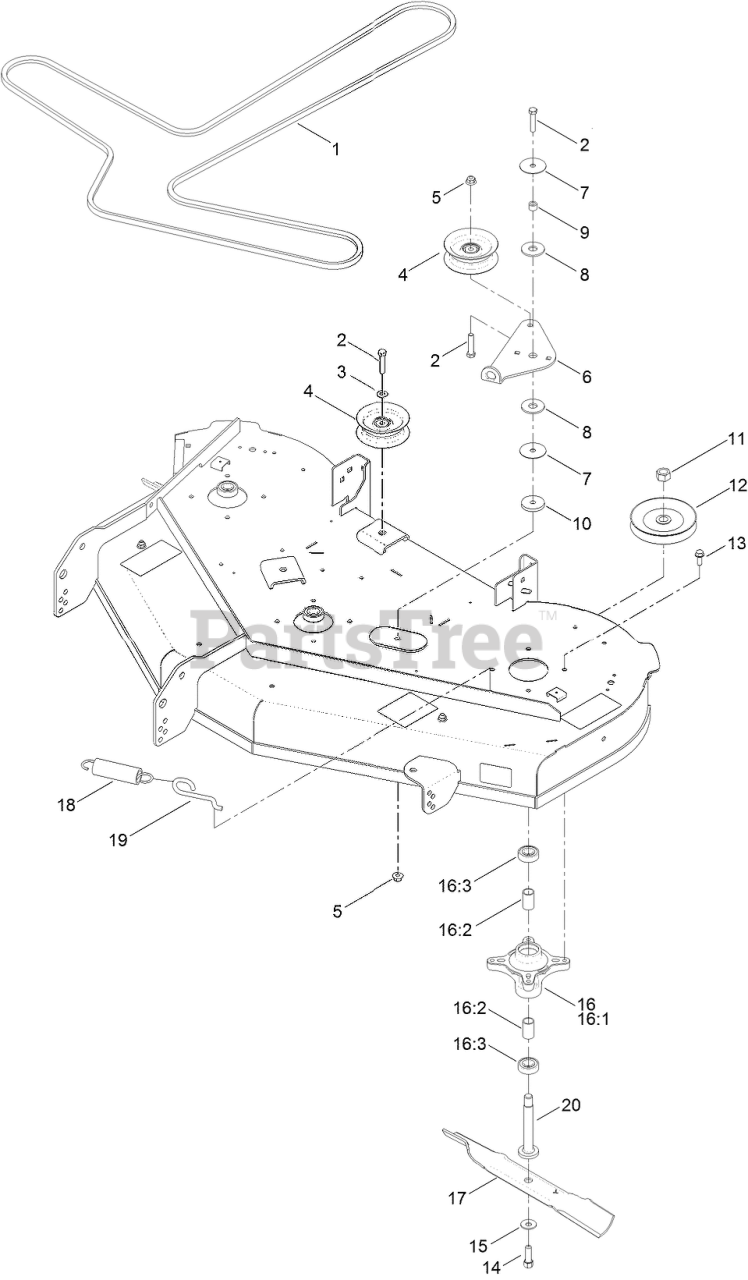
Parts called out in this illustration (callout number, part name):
1	V-BELT
2	SCREW-HH
3	WASHER-FLAT
4	PULLEY-IDLER, FLAT
5	NUT-HF, NI
6	ARM-IDLER
7	WASHER
8	WASHER-FRICTION, COMPOSITE
9	SPACER
10	WASHER-PLAIN
11	NUT-HEX
12	PULLEY
13	SCREW-TAPTITE
14	SCREW-HH
15	WASHER-BELLEVILLE
16	SPINDLE ASM
16:1	SPINDLE
16:2	SPACER
16:3	BEARING-BALL
17	BLADE-HI LIFT
18	SPRING-EXTENSION
19	HOOK-RETURN, SPRING
20	SHAFT-SPINDLE
